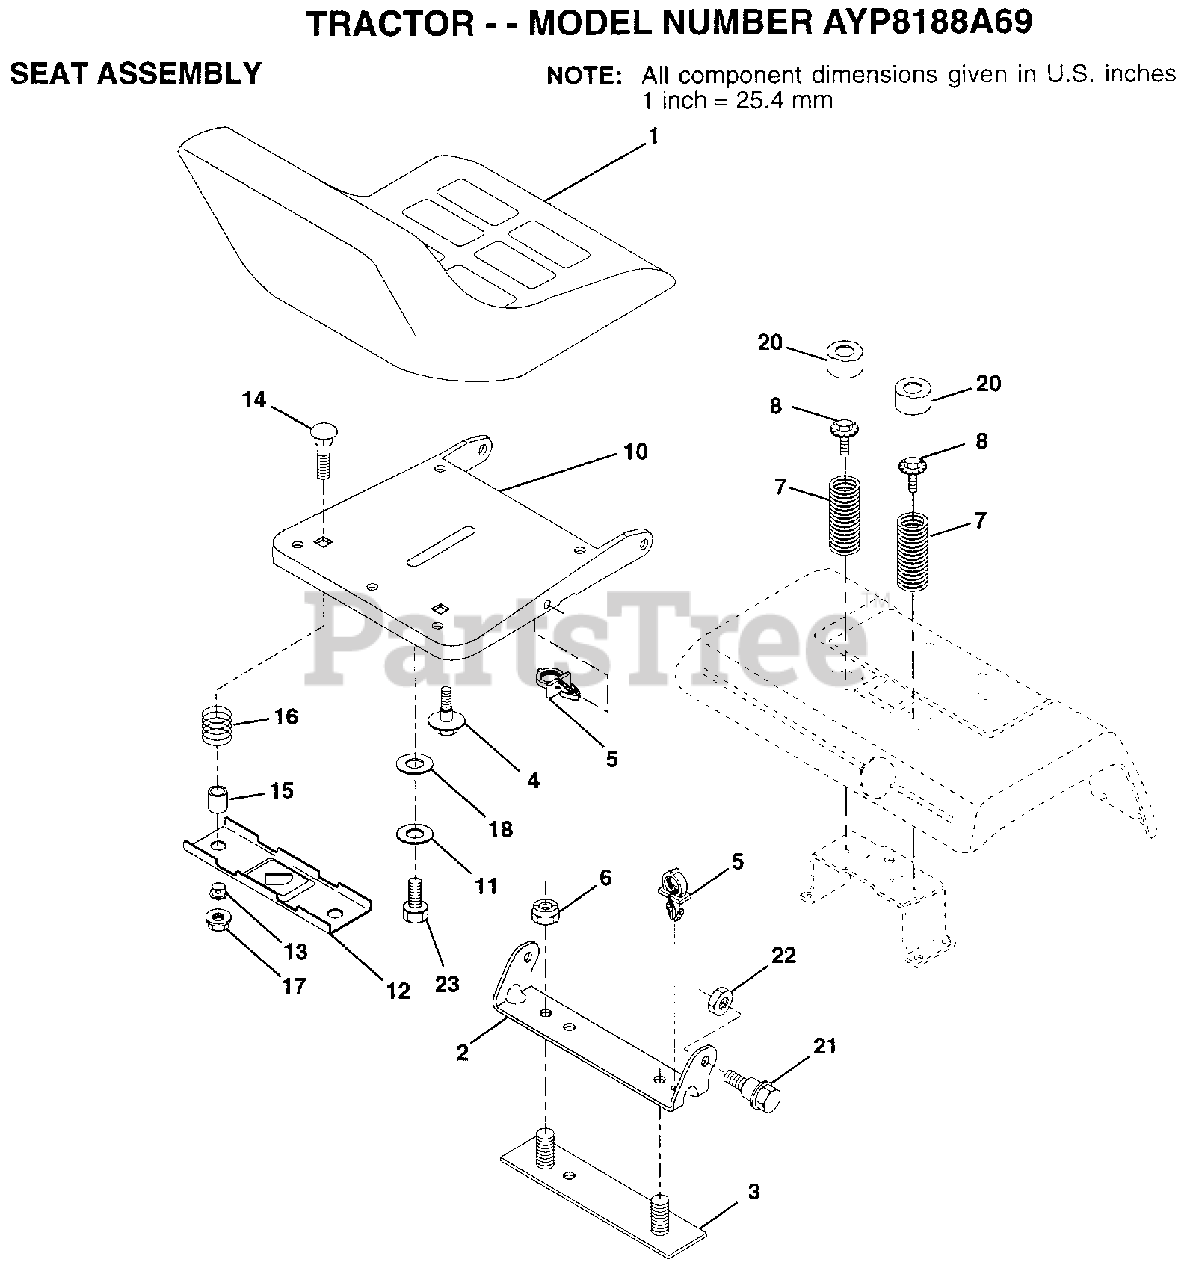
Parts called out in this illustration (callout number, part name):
1	SEAT.2400/1416.BK
2	BRACKET PVT SEAT
3	STRAP ASM FENDER
4	"BOLT,SHOULDER"
5	CLIP.PUSH-IN.HING
7	SPRING COMPRESSIO
8	BOLT.5/16-18.UNC
11	LOCKWASHER
12	BRKT SWITCH
13	BUSHING
15	SPLIT SPACER
16	SPRING
18	WASHER
20	CAP SPRING
21	BOLT.SHLD.5/16-18
23	BOLT
